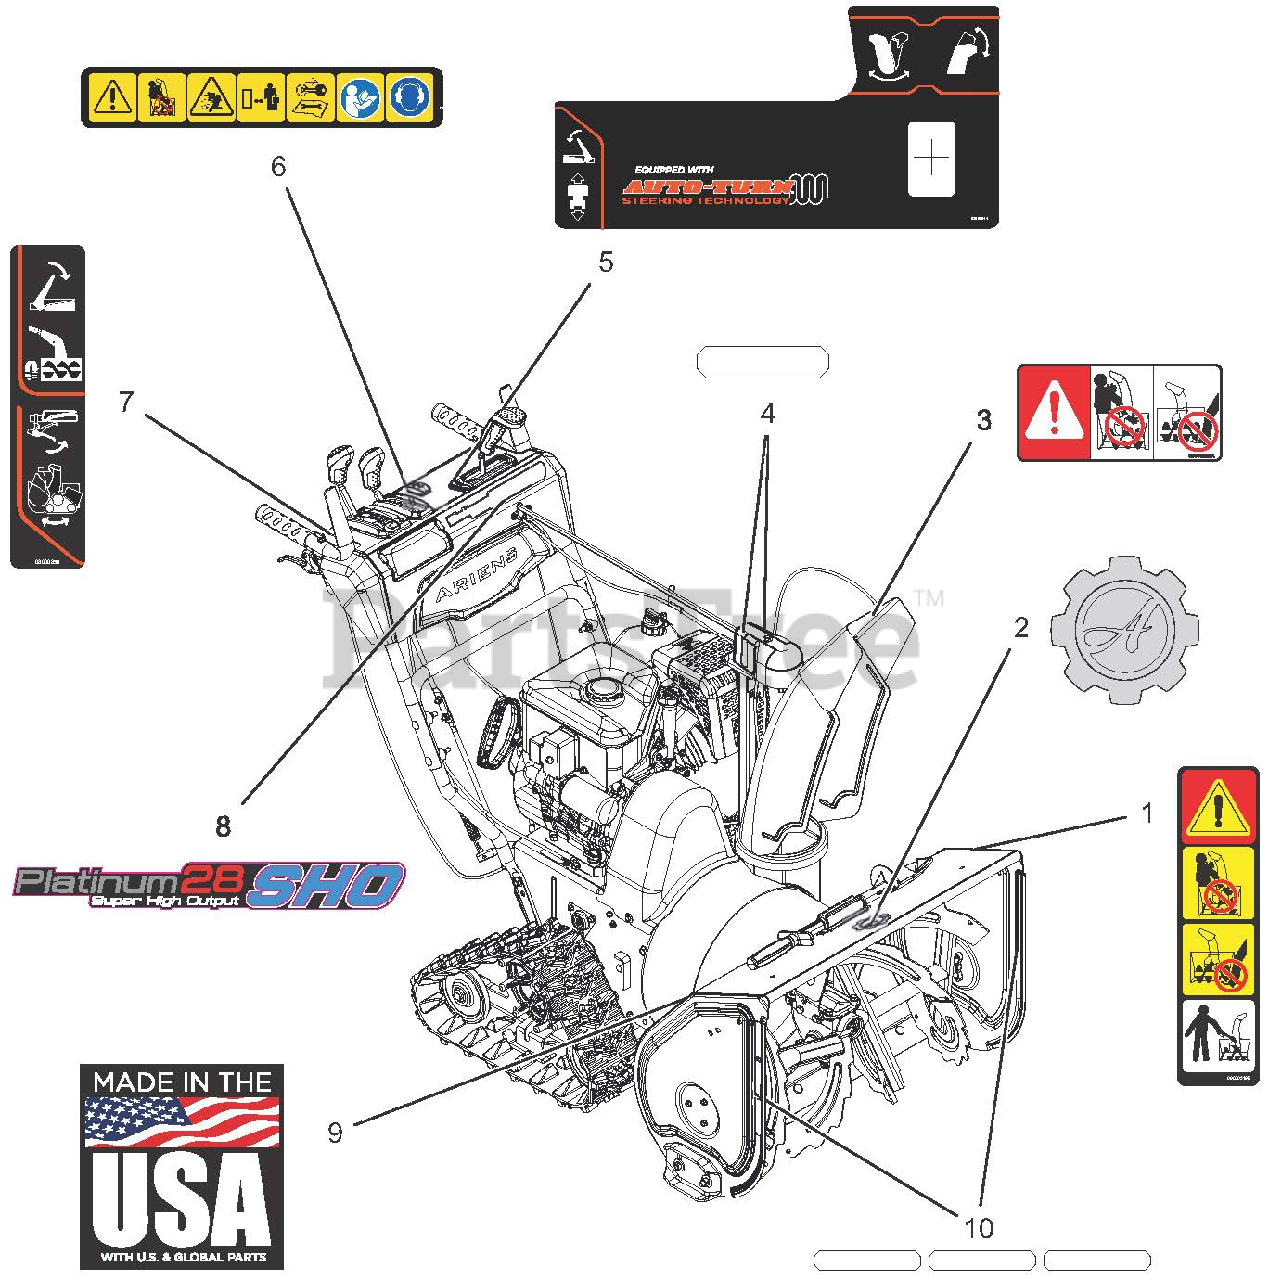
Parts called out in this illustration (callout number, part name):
1	DECAL, DANGER - ROTATING PARTS
2	DECAL, ARIENS-GEAR BADGE
3	DECAL, DANGER
4	DECAL,REFLECTIVE,GEAR COVER
5	DECAL,CONTROL-LG QT2
6	DECAL,DASH - SAFETY
7	DECAL,CONTROL-RH TRACK
8	DECAL, DASH, PLATINUM 28 SHO
9	DECAL, MADE IN USA
10	DECAL,REFLECTIVE,HOUSING
